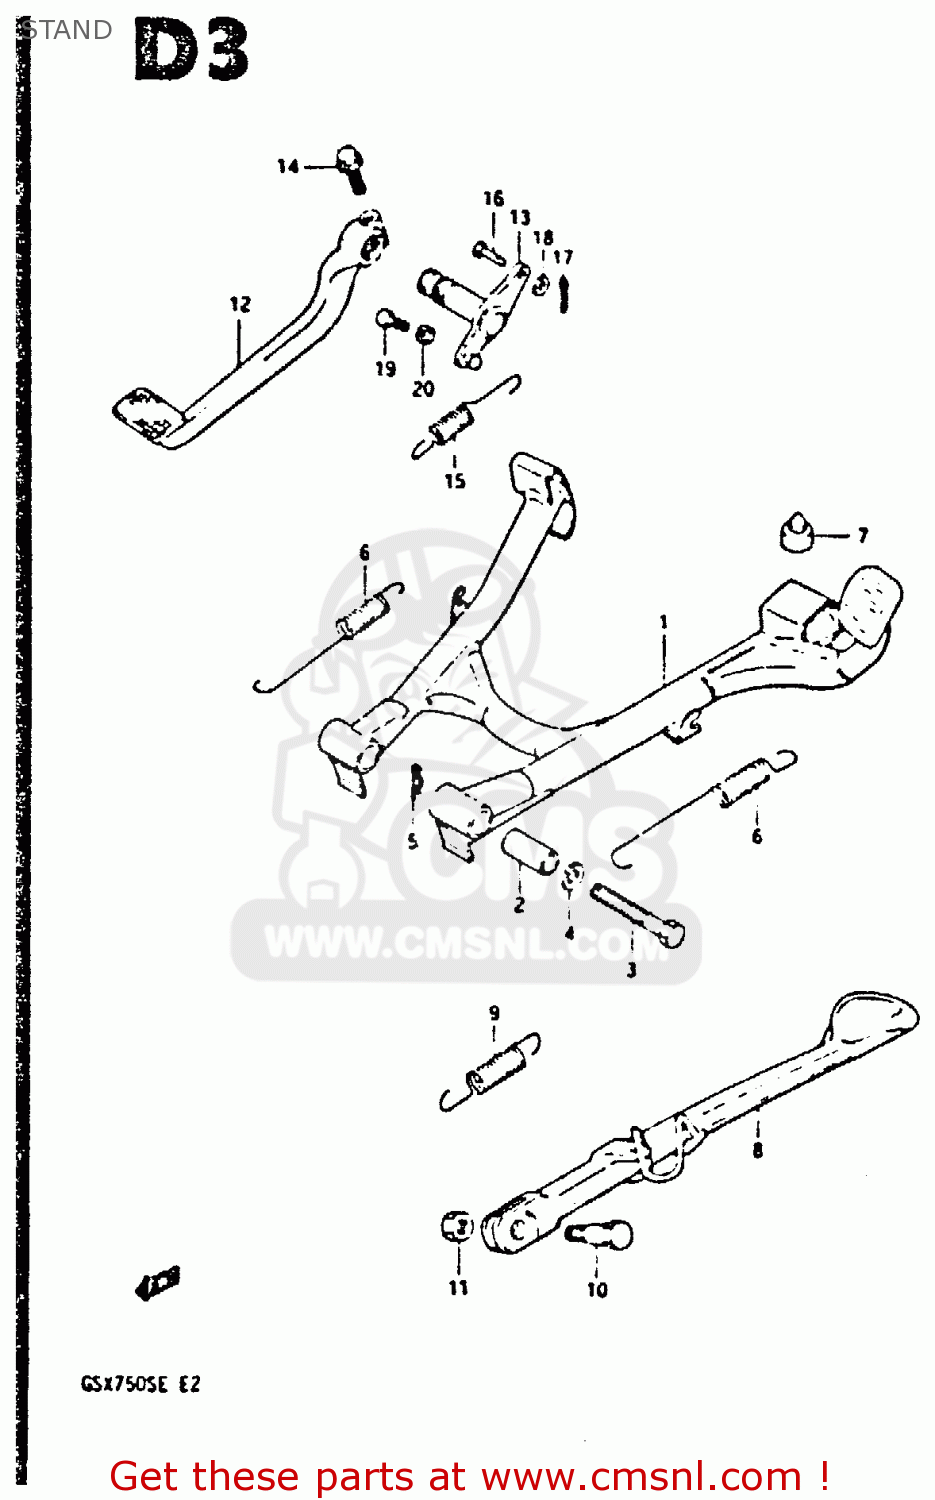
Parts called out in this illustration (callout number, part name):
1	STAND,CENTER
2	SPACER(10X16X38.8)
3	BOLT
4	LOCK WASHER
5	CLIP
6	SPRING
7	CUSHION
8	STAND, PROP (GOLD)
9	SPRING
10	BOLT(10X32)
11	NUTM10X1.25X8
12	PEDAL, BRAKE
13	ARM, BRAKE PEDAL ROD
14	BOLT
15	SPRING
16	PIN
17	PIN
18	WASHER
19	BOLT
20	NUT
